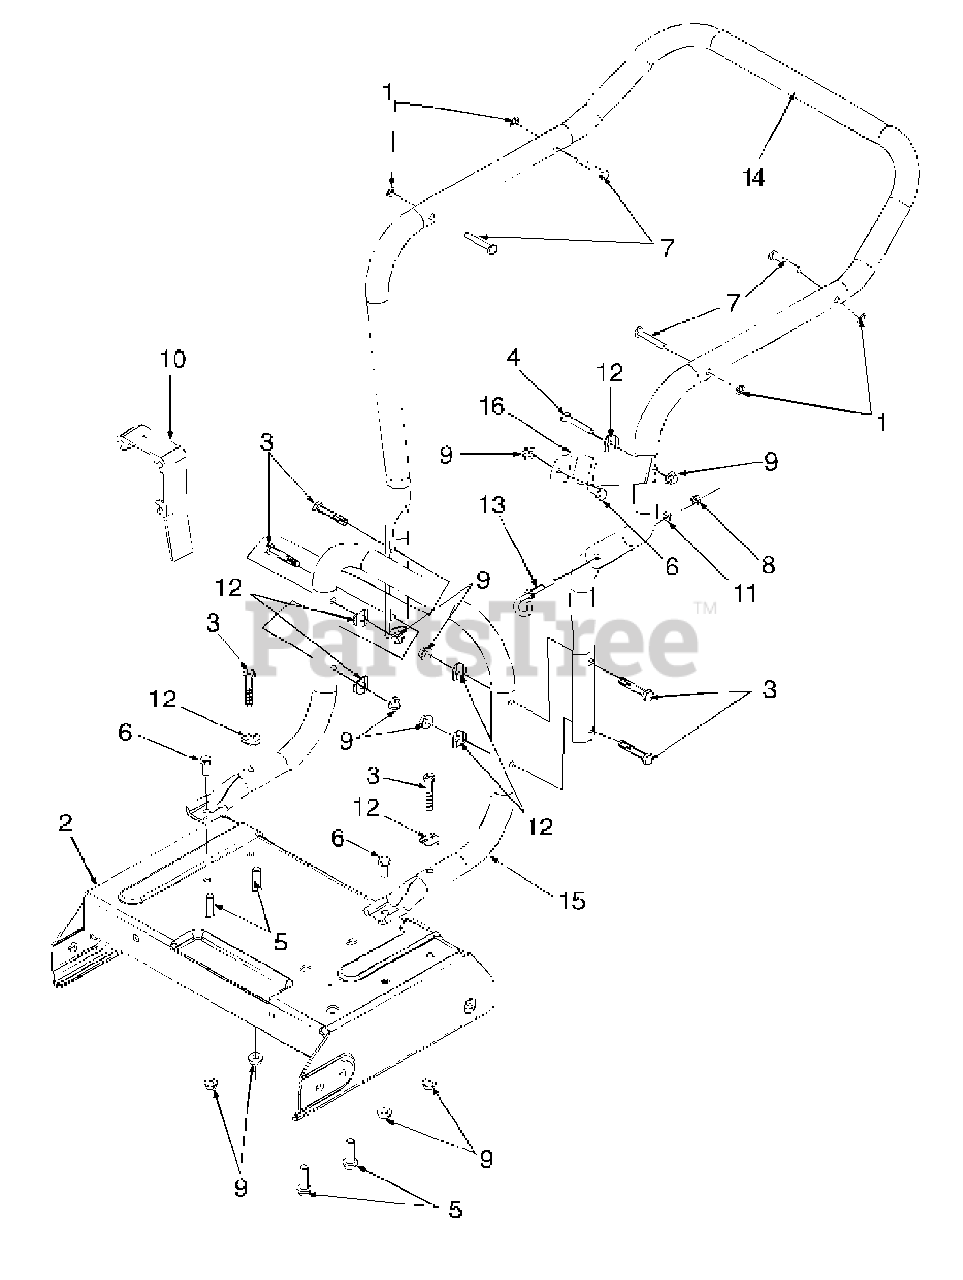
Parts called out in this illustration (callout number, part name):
1	Nut, Push
4	Screw, Hex Cap, 5/16-18 x 1.50
5	Screw, Hex Wash. Hd. Tapp, 3/8-16 x 1.25
6	Screw, Hex Cap, 5/16-18 x .75
7	Pin, Stud, .250 x 1.75
8	Nut, Hex, 1/4-28
9	Nut, Hex Flange Lock, 5/16-18
10	Adapter, Mounting
11	Washer, Lock, 1/4
12	Washer, Saddle, .32 ID x .93 OD
13	Bolt, Eye
14	Handle, Upper
15	Handle, Lower
16	Bracket, Chute Stabilizing
